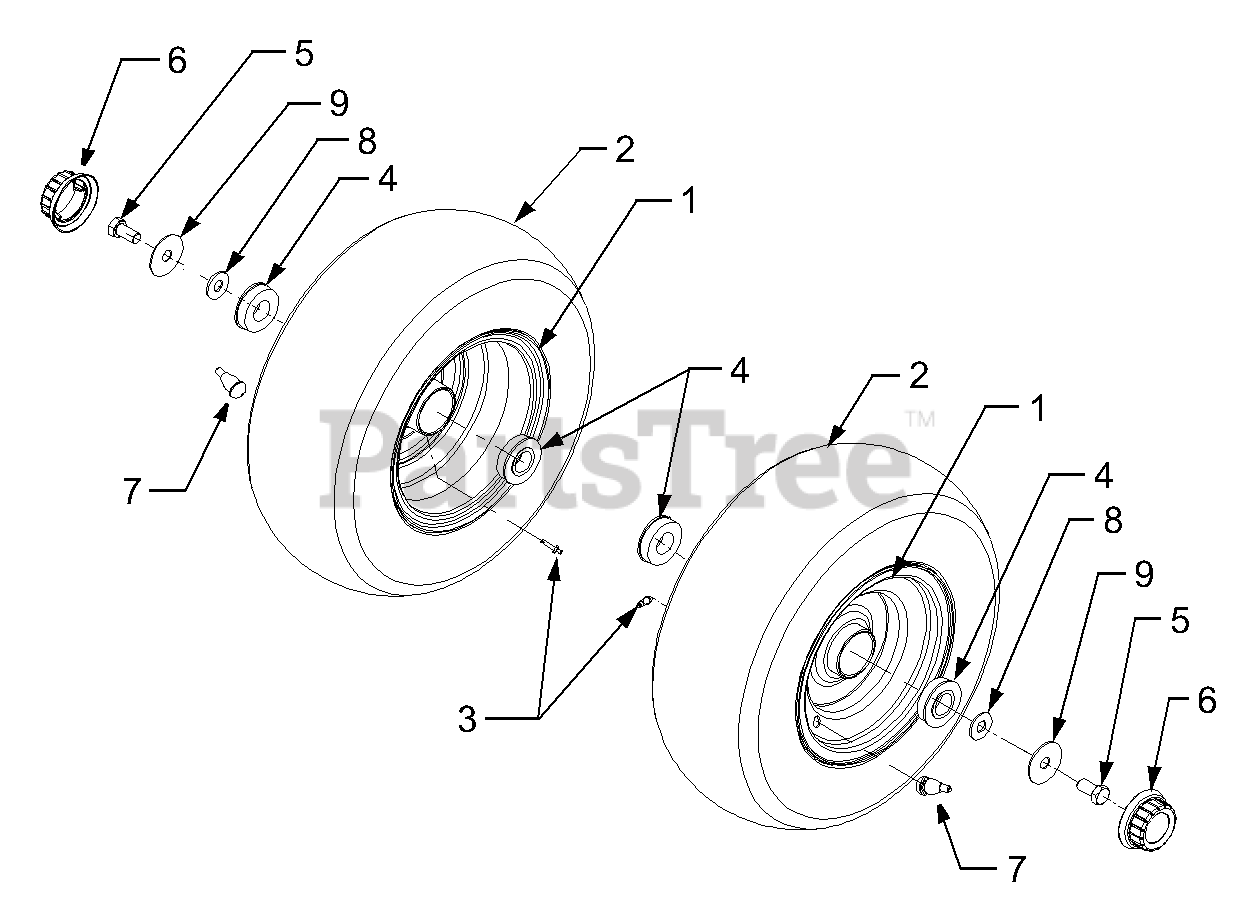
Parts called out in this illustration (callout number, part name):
1	Rim Assembly, Wheel
2	Tire, Turf, 16 x 6.5 x 8.0
3	Lube Fitting
4	Bearing, Ball
5	Screw, Hex Cap, 1/2-13 x 1.0 GR5
6	Hubcap
7	Valve, Tubeless Air
8	Washer, Flat, .531 x 1.25 x .1
9	Washer, Flat, .535 x 1.92 x .060
